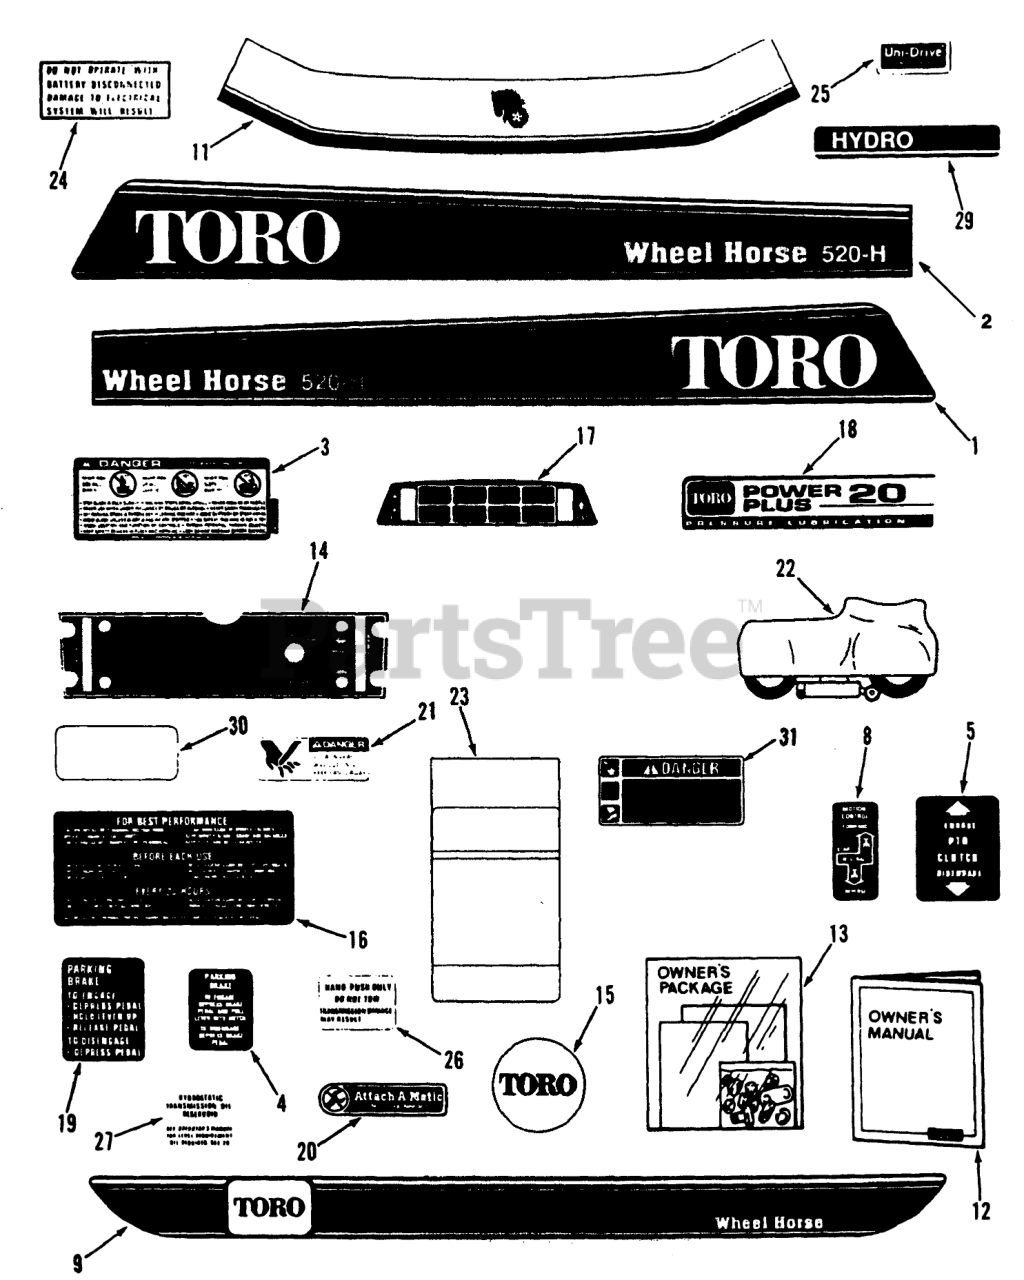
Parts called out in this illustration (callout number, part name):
1	DECAL HOOD 520H, RH
2	DECAL HOOD 520H, LH
3	DECAL-DANGER
4	DECAL-PARKING BRAKE
5	DECAL PTO CLUTCH
8	DECAL-MOTION CONTROL
9	DECAL-FENDER
11	DECAL-FRONT HOOD
12	Manual-Operator-s Tractor
13	Loose Parts Package
14	DECAL-FRONT PANEL
15	NAME-PLATE TORO LOGO
16	DECAL-REAR HOOD
17	DECAL-IND LIGHTS
18	DECAL-PWR PLUS 20 PL
19	DECAL-PARKING BRAKE
20	Decal-Attac-O-Matic
21	DECAL-DANGER
22	Plastic Cover
23	MAINTENANCE-DECAL
24	DECAL ELECT SYSTEM
25	Decal-Unidrive
26	DECAL-DO NOT TOW
27	Decal-Danger
29	DECAL-MODEL HYDRO
30	DECAL-OVERLAY
31	DECAL-DANGER
